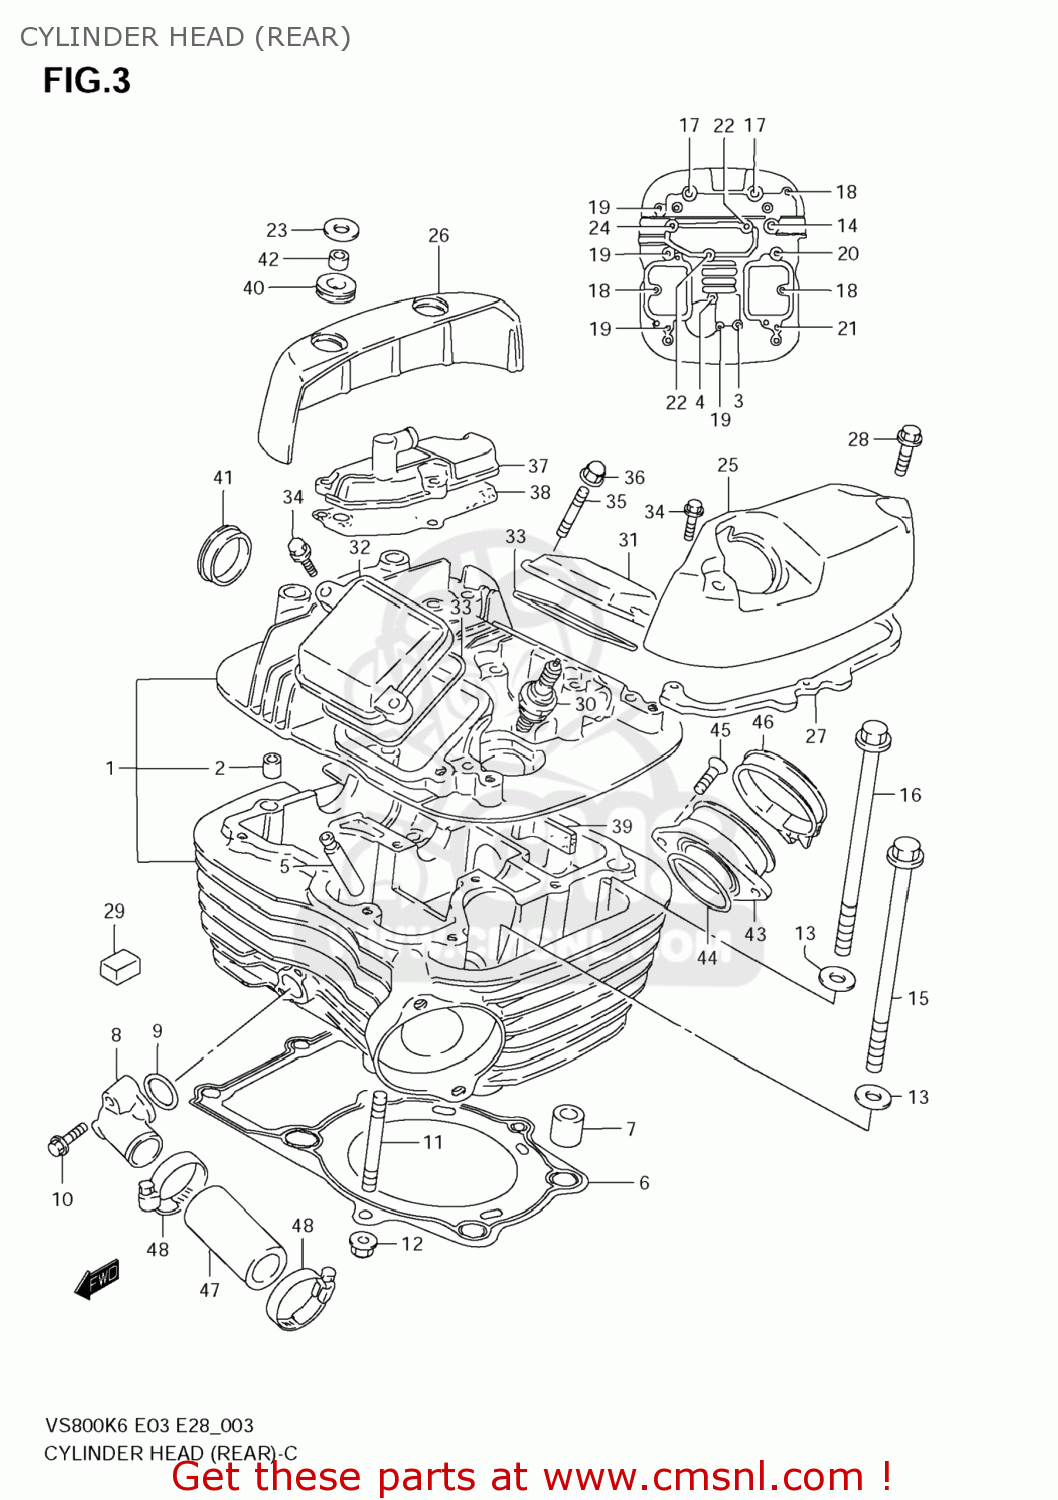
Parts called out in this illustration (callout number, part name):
1	HEAD ASSY,CYLINDER RR
2	PIN(8.4X11X14)
3	BOLT(6X50)
4	BOLT(6X55)
5	GUIDE,VALVE
6	GASKET,CYLINDER HEAD RR (NAS)
7	PIN
8	UNION,CYLINDER HEAD WATER
9	O RING(D:2.4,ID:17.8)
10	BOLT
11	BOLT,STUD
12	NUT
13	WASHER(10.5X22X2.3)
14	BOLT(8X140)
15	BOLT(10X155)
16	BOLT(10X165)
17	BOLT(8X245)
18	BOLT
19	BOLT
20	BOLT
21	BOLT
22	BOLT(6X55)
23	WASHER(8.5X24X1.6)
24	BOLT
25	CAP,CYLINDER HEAD COVER RR,L
26	CAP,CYLINDER HEAD COVER RR,R
27	CUSHION,RR,L CAP
28	BOLT
29	PAD
30	SPARK PLUG X22E
31	CAP,INSPECTION INTAKE
32	CAP,INSPECTION EXHAUST
33	GASKET,INSPECTION CAP (NAS)
34	BOLT
35	BOLT,STUD
36	NUT
37	COVER,BREATHER
38	GASKET,BREATHER COVER (NAS)
39	PLATE,HEAD COVER RR
40	CUSHION
41	PLUG(OD:30)
42	BUSH
43	PIPE ASSY,INTAKE RR
44	O RING(D:2.4,ID:39.7)
45	BOLT
46	CLAMP
47	HOSE,CYLINDER HEAD JOINT
48	CLAMP
